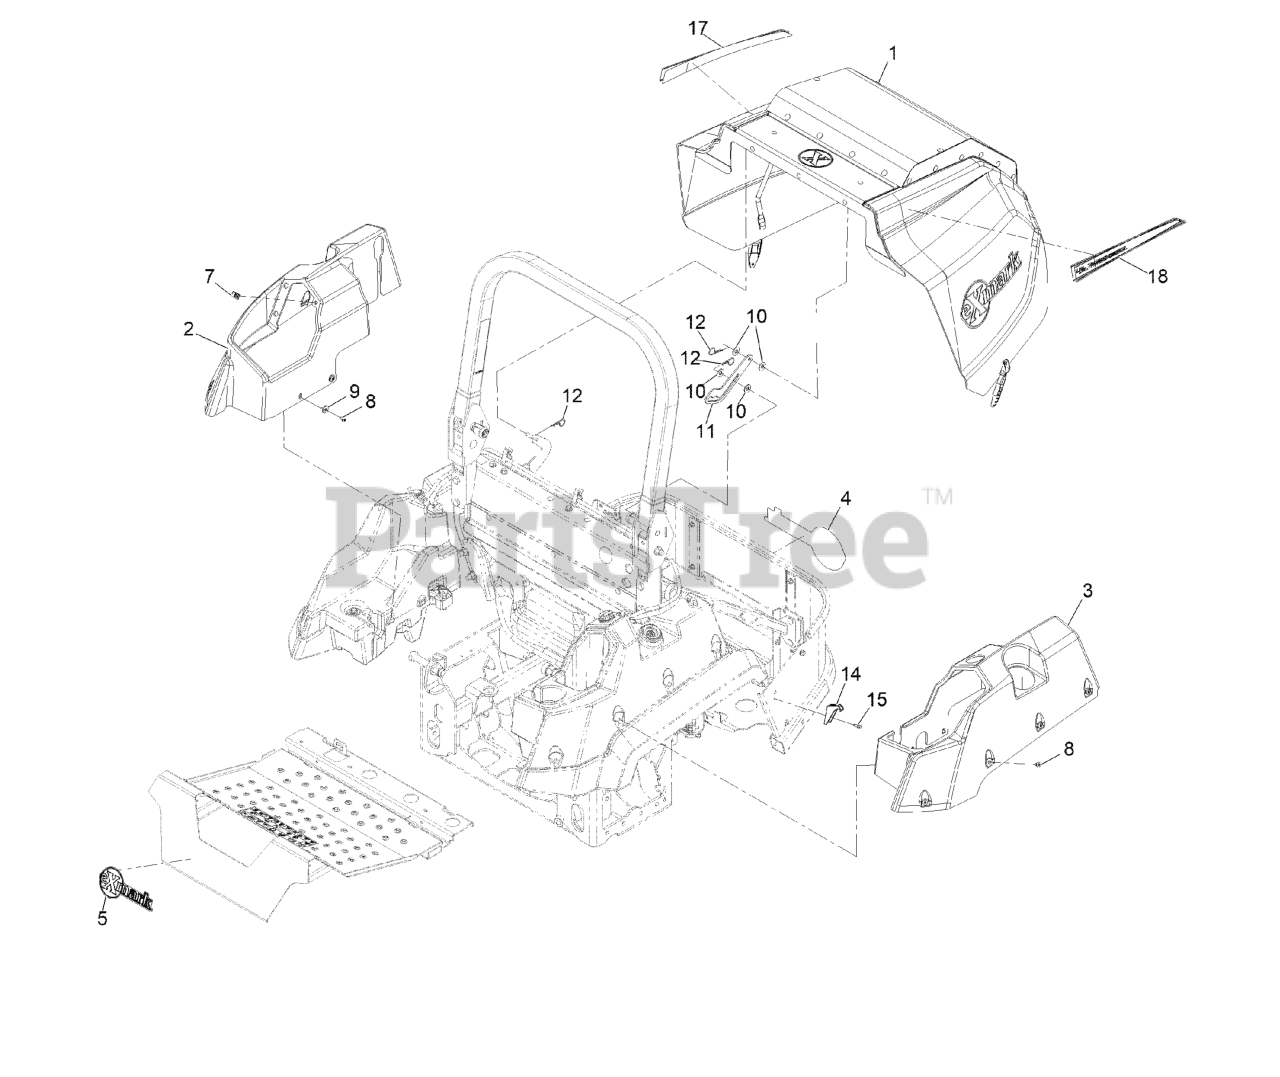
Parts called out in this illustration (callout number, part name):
1	ASM, HOOD LZSD
2	COVER-TANK, RH
3	COVER-TANK, LH
4	DECAL-EXMARK
5	DECAL-EXMARK
8	SCREW-TORX
9	WASHER-FLAT
10	WASHER-FLAT
11	PROP-HOOD
12	PIN-COTTER, HAIR
14	LATCH-CATCH
15	SCREW-HWH
17	DECAL-TURBO DIESEL-RH
18	DECAL-TURBO DIESEL-LH
